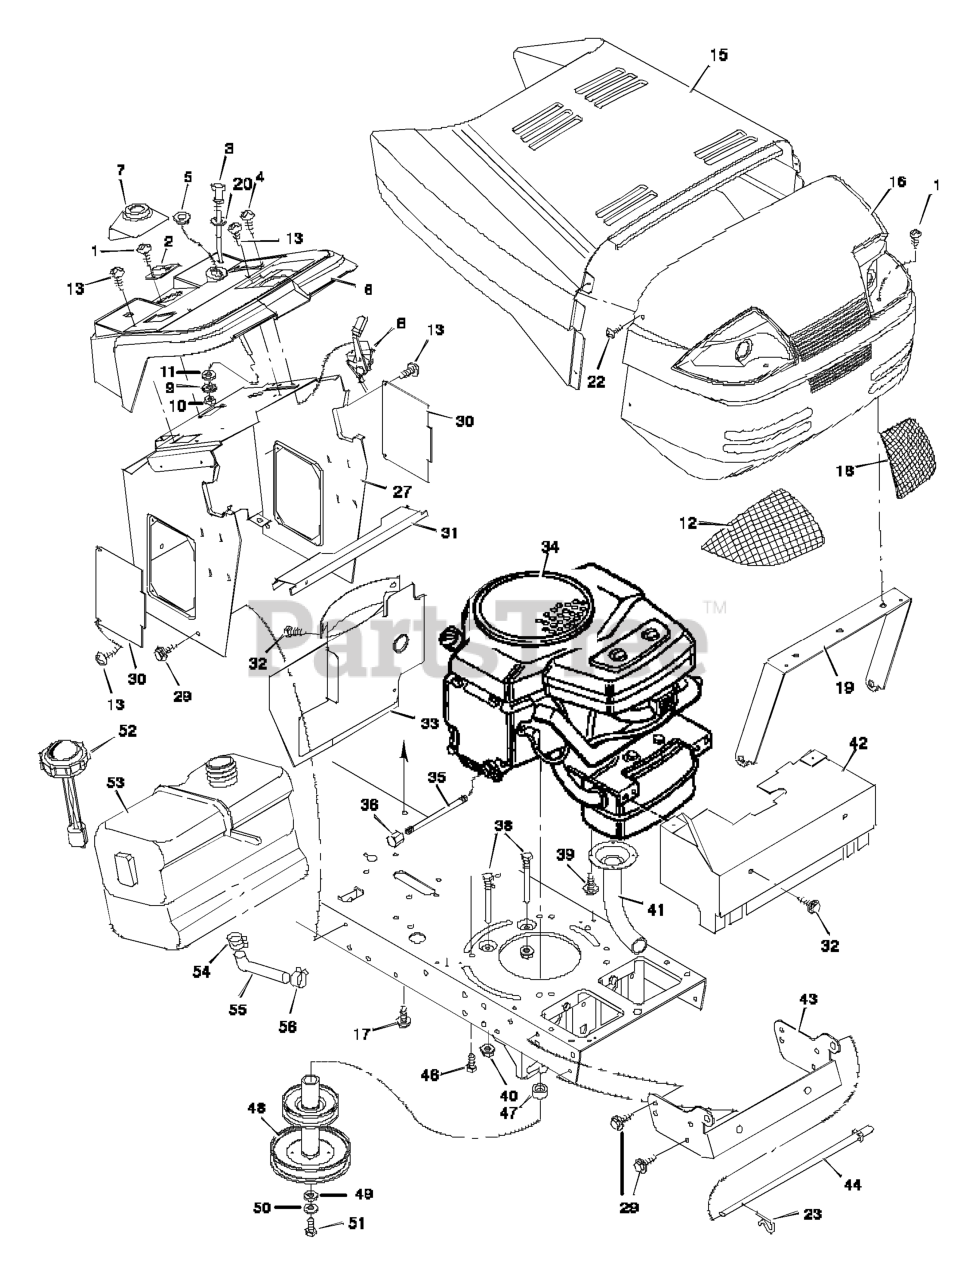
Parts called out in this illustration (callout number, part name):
2	Bearing, Steering Post
3	Cable, Choke
5	Bushing
7	Support, Bellows
8	Throttle Control
9	Lockwasher
10	Nut, Hex
12	Lens, Right
13	Screw
15	Hood
16	Grille
18	Lens, Left
19	Brace, Grille
20	Washer
23	Pin, Hair
27	Console Assembly
30	Panel, Side Access
31	Support, Fuel Tank
32	Screw
33	Baffle, Rear Heat
34	Engine *
35	Oil Drain Extension
36	Oil Drain Cap
38	Guide, Belt
40	Locknut, Flange
41	Pipe, Exhaust
42	Shield, Heat
43	Support, Grille
44	Rod, Pivot
46	Bolt, Hex
47	Spacer, Engine
48	Pulley Assembly, Stack
50	Lockwasher
51	Bolt, Hex
52	Cap, Fuel
53	Fuel Tank
54	Clamp, Hose
55	Fuel Line
56	Clamp, Hose
